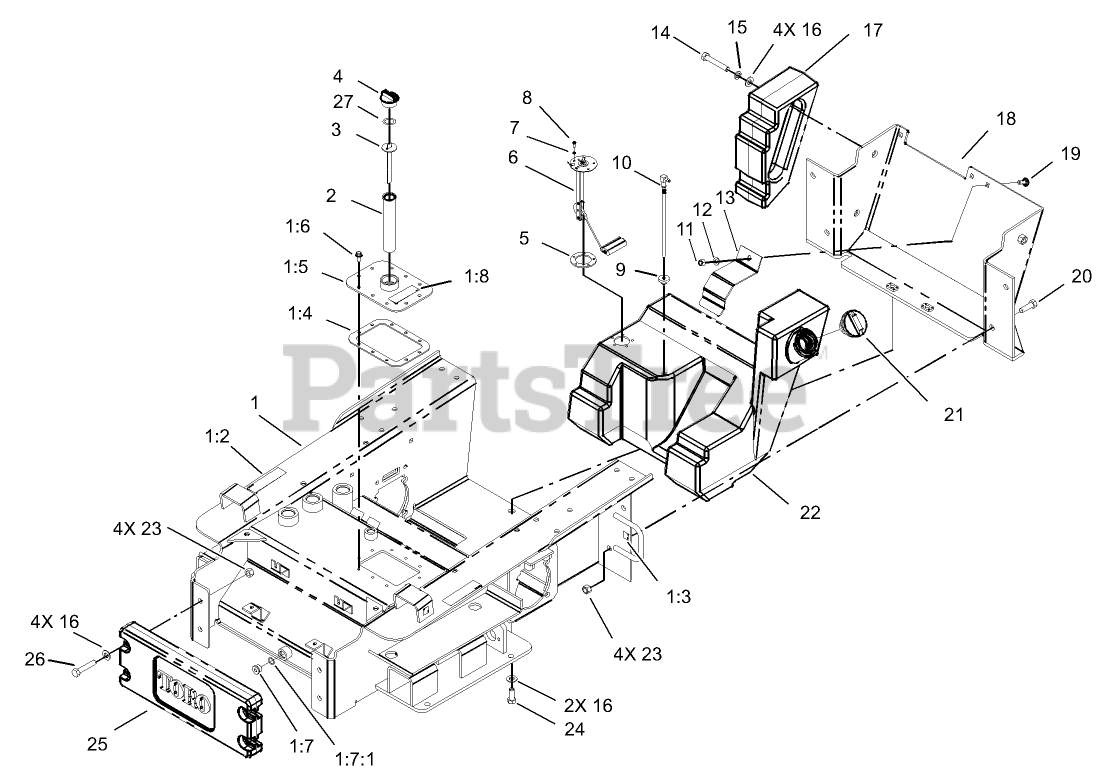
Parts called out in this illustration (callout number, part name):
1	CHASSIS ASM
1:2	DECAL-PINCH
1:3	DECAL-POINT, LIFT
1:4	GASKET-COVER, ACCESS
1:5	TANK COVER ASM
1:6	SCREW
1:7	PLUG-HEX
1:7:1	O-RING
1:8	DECAL-OIL, HYD
2	FILTER-SCREEN
3	DIPSTICK-OIL
4	PLUG-PLASTIC
5	GASKET-SENDER, FUEL
6	SENDER-FUEL
7	WASHER-LOCK
8	SCREW-PPH
9	BUSHING
10	PIPE-STAND
11	NUT-LOCK, NI
12	WASHER-FLAT
13	CLAMP-TANK, FUEL
14	SCREW-HH
15	WASHER-LOCK
16	WASHER-FLAT
17	COUNTERWEIGHT-REAR
18	REAR FRAME COVER ASM
19	SCREW-CARR
20	SCREW-HH
21	CAP-FUEL
22	TANK-FUEL
23	NUT-LOCK, NI
24	SCREW-HH
25	COUNTERWEIGHT-FRONT
26	SCREW-HH
27	O-Ring
